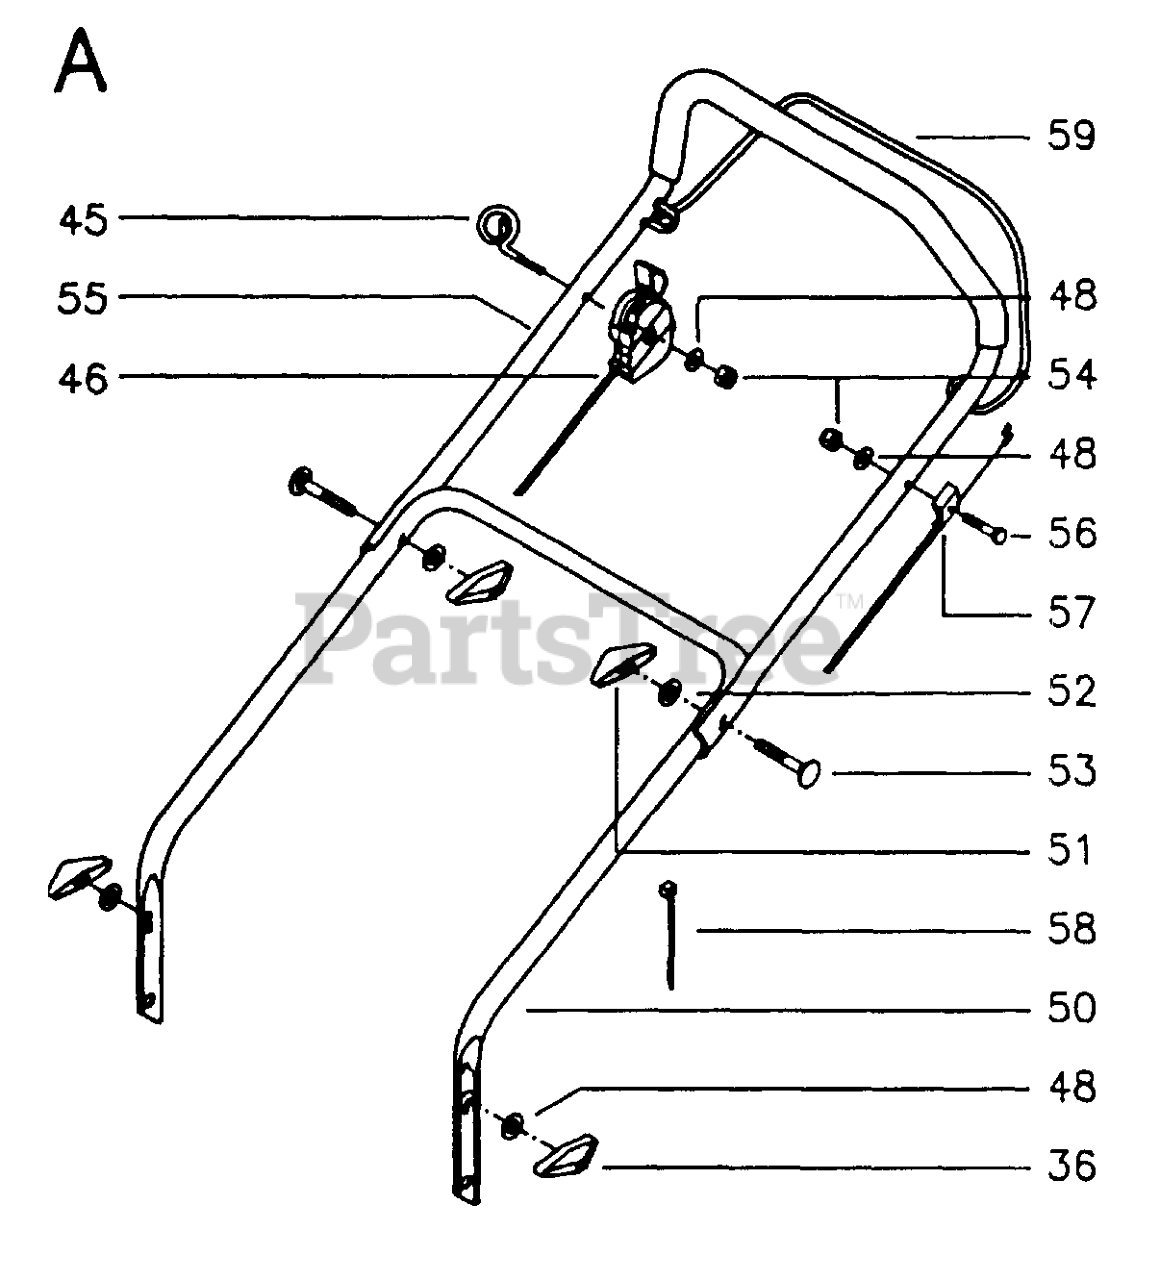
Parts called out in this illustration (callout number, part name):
46	CONTROL
51	WINGNUT
52	WASHER - 15X7.3X1.6
54	LOCKNUT M6
56	BOLT FLANGE
57	CONTROL CABLE
